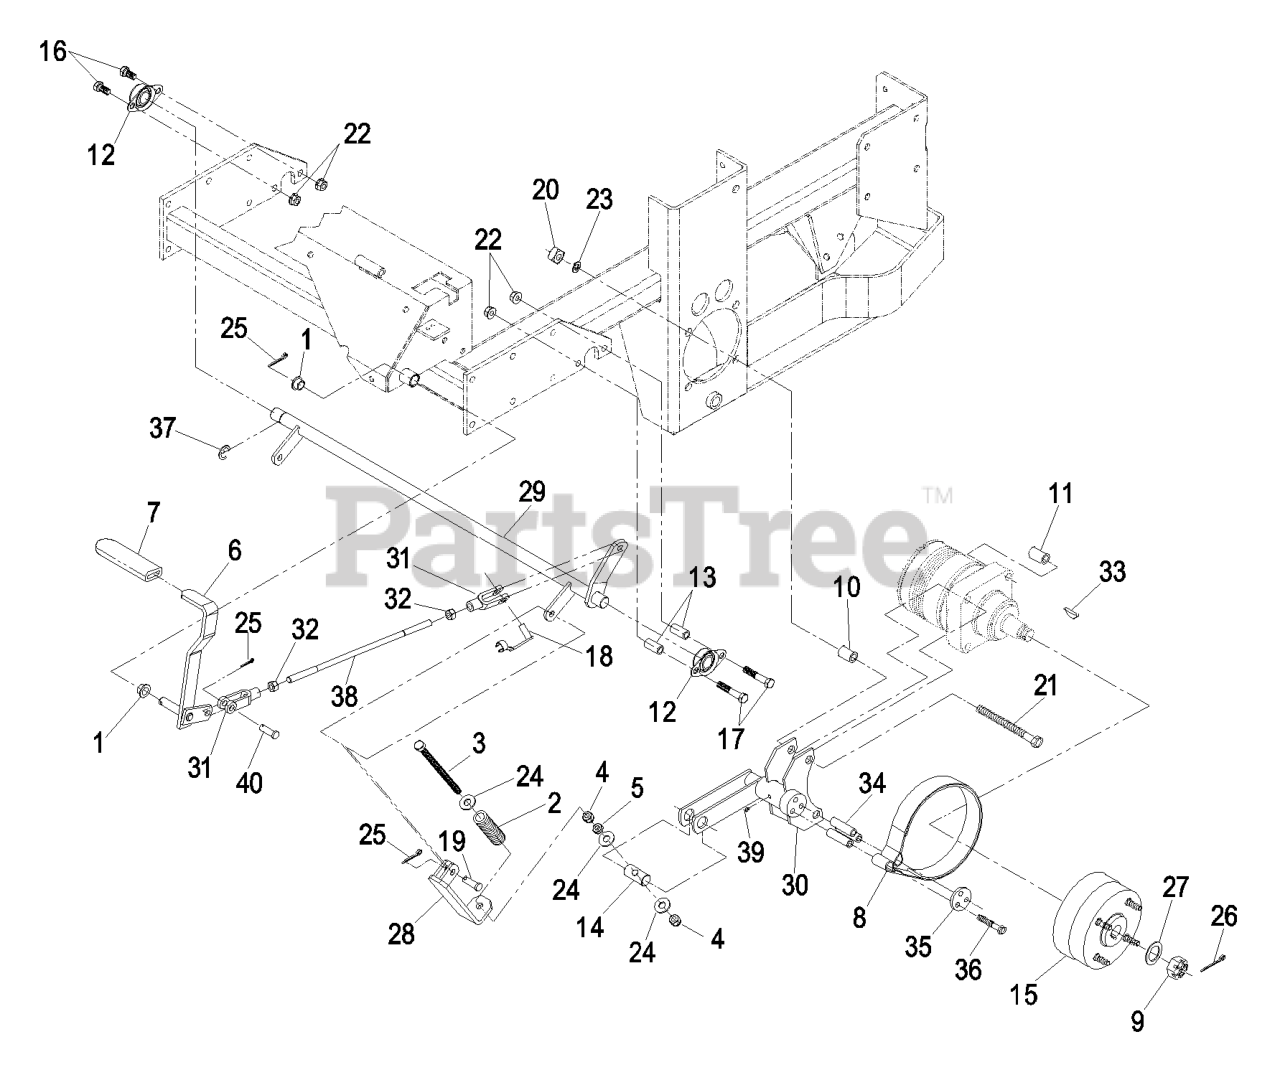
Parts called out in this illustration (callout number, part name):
1	BEARING-CONTROL
2	SPRING-BRAKE
3	BOLT-TAP, HH
4	NUT-LOCK, NI
5	NUT-JAM
6	BRAKE LEVER AND GRIP ASM
7	GRIP-LEVER
10	SPACER-WHEEL, SHORT
11	SPACER-WHEEL, LONG
12	BEARING-FLANGE, SIDE
13	SPACER-RETAINER, BRAKE
14	PIN-TRUNION
15	WHEEL HUB ASM
16	SCREW-HH
17	SCREW-HH
18	PIN-SPRING, CLEVIS
19	PIN-CLEVIS
21	SCREW-HH
22	NUT-HHF, WHIZ
23	WASHER-LOCK
24	WASHER-FLAT
25	PIN-COTTER
26	PIN-COTTER
27	WASHER-SPACER
28	LINKAGE-BRAKE, LOWER
29	SHAFT-BRAKE
30	BRAKE-WIDE
31	YOKE-LINKAGE, BRAKE
32	NUT-HEX
33	KEY-WOODRUFF
35	RETAINER-BAND, BRAKE
36	SCREW-HH
38	ROD-BRAKE
39	FITTING-GREASE
40	PIN-CLEVIS
